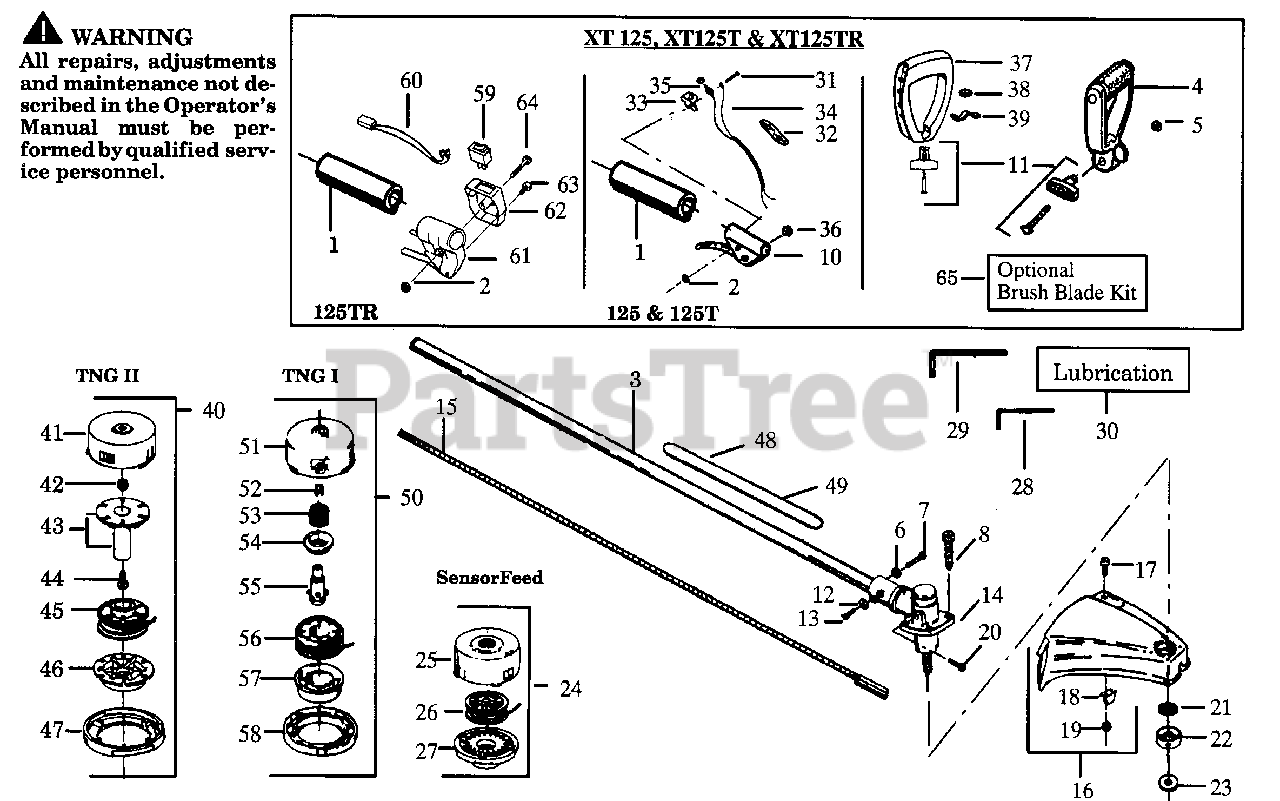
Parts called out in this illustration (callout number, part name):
1	Drive Shaft Pad Model XT125TR,XT125,XT125T
2	Nut Model XT125TR,XT125,XT125T
3	Drive Shaft Housing
4	Handle Model XT125TR,XT125,XT125T
5	Nut Model XT125TR,XT125,XT125T
6	Lockwasher
8	Screw-Use w/Plastic Shield only
10	Throttle Lever Ass'y. (Inc.2,31) Model XT125TR,XT125,XT125T
11	"T" Handle Ass'y. Model XT125TR,XT125,XT125T
12	Lockwasher
14	Gear Box Ass'y.
15	Drive Shaft
16	Shield Kit Ass'y. (Inc.17,18,19)
18	Line Limiter
19	Locknut
22	Dust Cup
23	Grass Washer
24	Cutting Head Ass'y. (Inc.25-27)
25	Hub Ass'y.
26	Spool w/Line
28	Hex Wrench (5/32)
29	Hex Wrench (3/16)
30	Shaft Lubrication
31	Screw Model XT125,XT125T
32	Terminal Lock Model XT125,XT125T
33	Switch Bracket Model XT125,XT125T
34	Wire Harness Ass'y. Model XT125,XT125T
35	Spacer Model XT125,XT125T
36	Nut Model XT125,XT125T
37	Handle Model XT125TR,XT125,XT125T
38	Nut Model XT125TR,XT125,XT125T
39	Clamp Model XT125TR,XT125,XT125T
40	Single Exit Cutting Head (Inc.41-47)
41	Hub Ass'y.
43	Locking Plate Kit
45	Spool w/Line
46	Release Button
48	Decal-Shaft Warning (Upper)
49	Decal-Shaft Warning (Lower)
50	Cutting Head Ass'y. (Inc.51-58)
51	Hub Ass'y.
52	Line Saver
54	Spring Cap
55	Drive Gear
56	Spool w/Line
57	Release Button
59	Rocker Switch Model XT125TR
60	Leadwire Model XT125TR
61	Ass'y Throttle Housing Model XT125TR
62	Switch Cover Model XT125TR
63	Screw (Short) Model XT125TR
64	Screw (Long) Model XT125TR
65	Optional Brush Blade Kit Model XT125TR, XT125,XT125T
